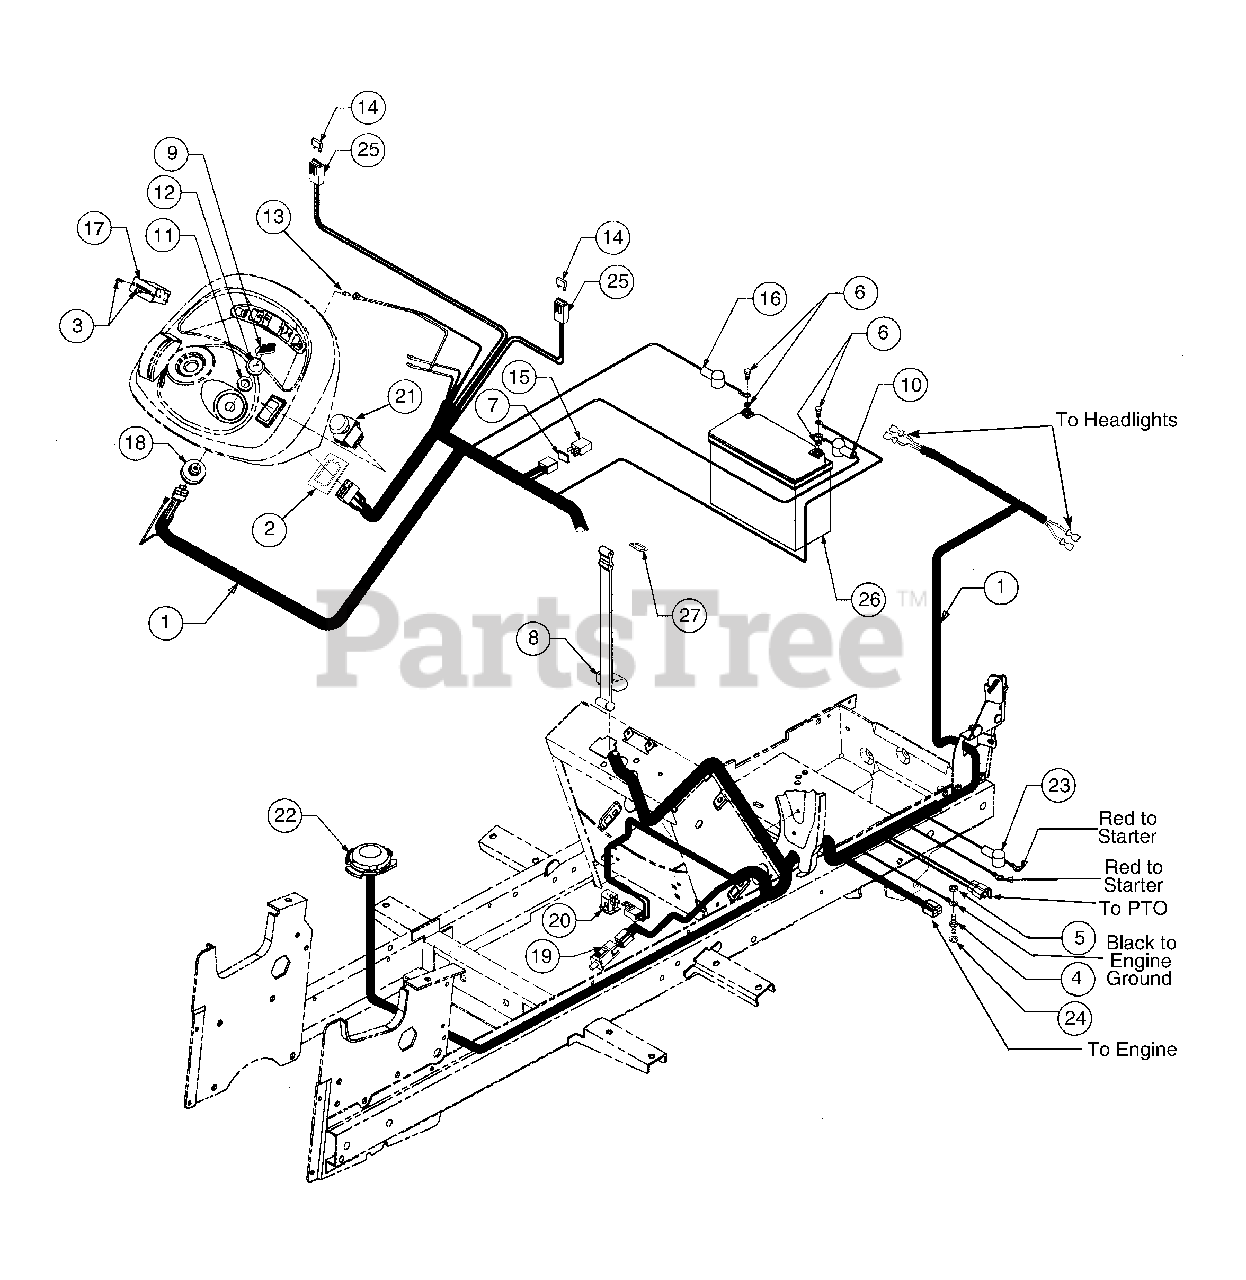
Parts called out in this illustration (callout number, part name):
1	Wire Harness, Main
2	Bracket, PTO Switch Retainer
3	Screw, Truss Hd Tapp, #6 x .62
4	Stud, Ground
5	Nut, Hex, 5/16-18 GR5
6	Battery Cable Hardware
7	Gasket, Silicone
8	Strap, Battery Retainer
9	Key, Ignition (Set of 2)
10	Cover, Terminal Black
11	Nut, Ignition Switch
12	Cap, Ignition Switch
13	Bulb, Indicator
14	Fuse, 25 Amp
15	Relay
16	Cover, Terminal Red
17	Hour Meter
18	Switch, Ignition
19	Switch, Interlock (Brake)
20	Switch, Snap Mount - Normally Closed
21	Switch, PTO
22	Switch, Seat
23	Cover, Terminal Red
24	Washer, External Lock, 5/16
25	Holder, Fuse w/Mounting Clip
26	Battery
27	Hook, Wire Rectangular
